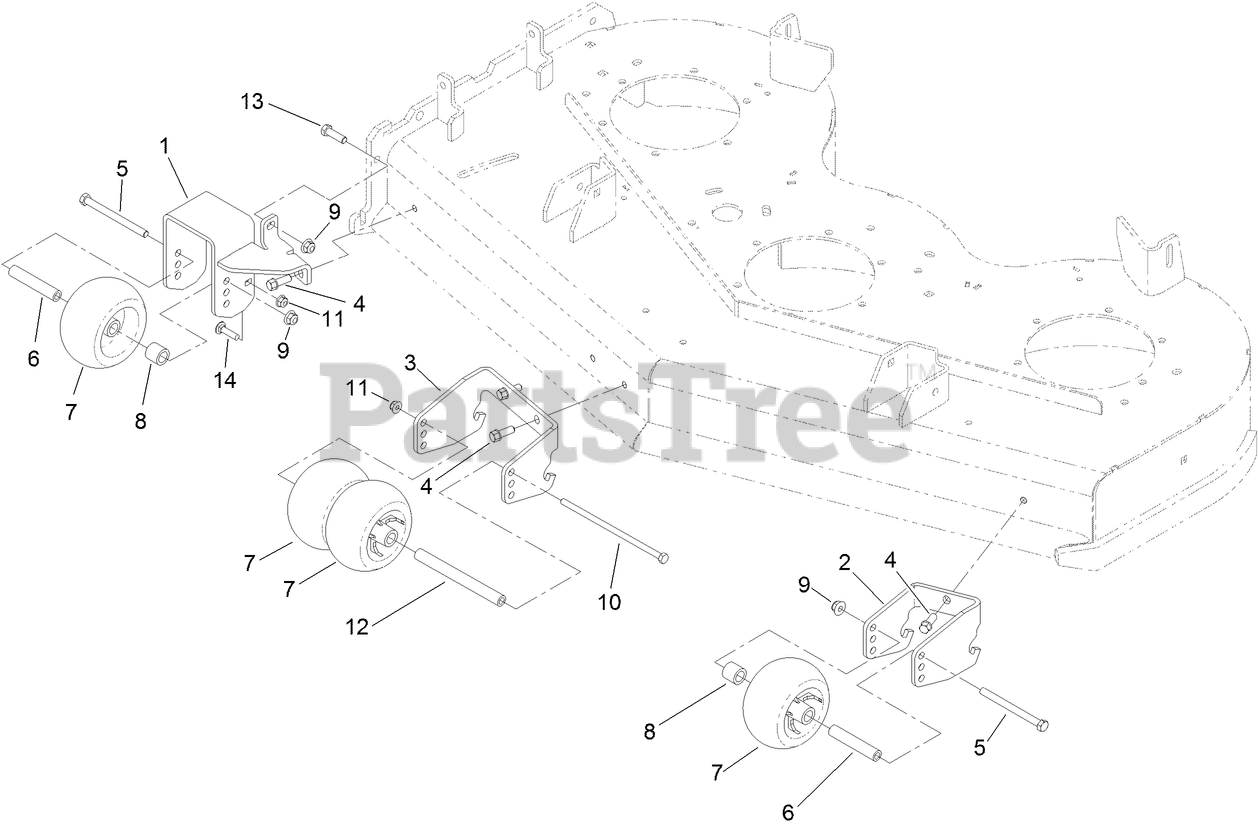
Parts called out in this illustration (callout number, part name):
1	BRACKET-WHEEL
2	BRACKET-WHEEL, LH
3	BRACKET-WHEEL, CENTER
4	SCREW-HWH
5	SCREW-HH
6	TUBE-SPANNER
7	ROLLER-SCALP, ANTI
8	SPACER-AXLE, REAR
9	NUT-HF, NI
10	SCREW-HH
11	NUT-HF, NI
12	SPACER-WHEEL
13	SCREW-HH
14	SCREW-CARR
